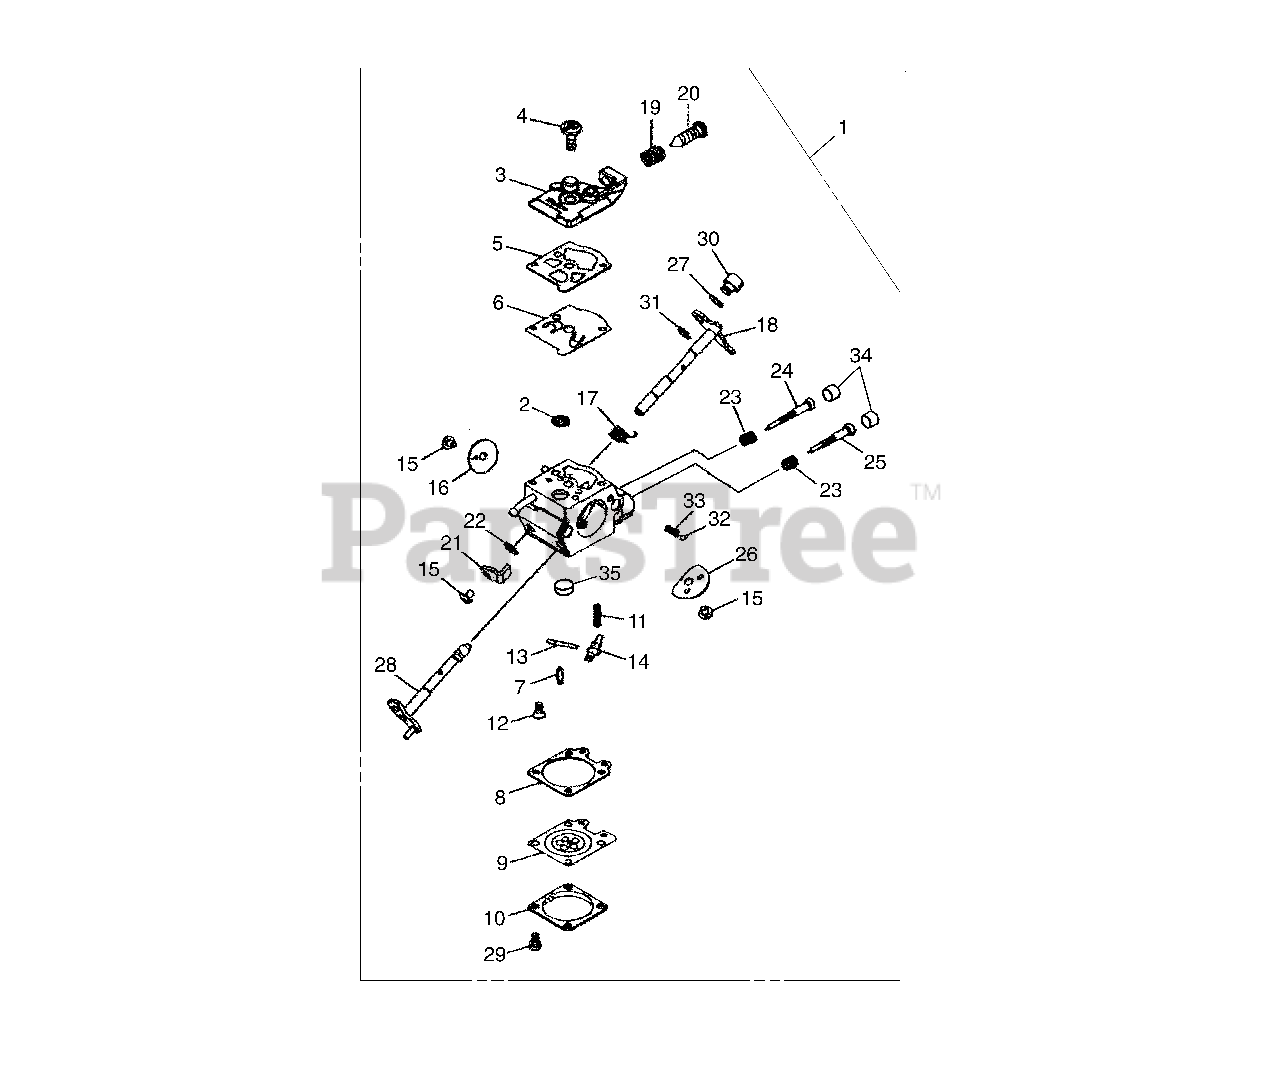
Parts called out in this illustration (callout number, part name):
1	CARBURETOR ASSY WTEA-4A
2	SCREEN
5	GASKET
6	DIAPHRAGM
7	VALVE INLET
8	GASKET
9	DIAPHRAGM
15	SCREW
16	VALVE, THROTTLE
18	SHAFT ASSY THROTTLE
20	SCREW, IDLE
21	LEVER THROTTLE
24	NEEDLE L
25	NEEDLE H
26	VALVE CHOKE
28	SHAFT ASSY CHOKE
29	SCREW ASSY
31	RING
33	CHOKE SPRING
34	CAP LIMITER
